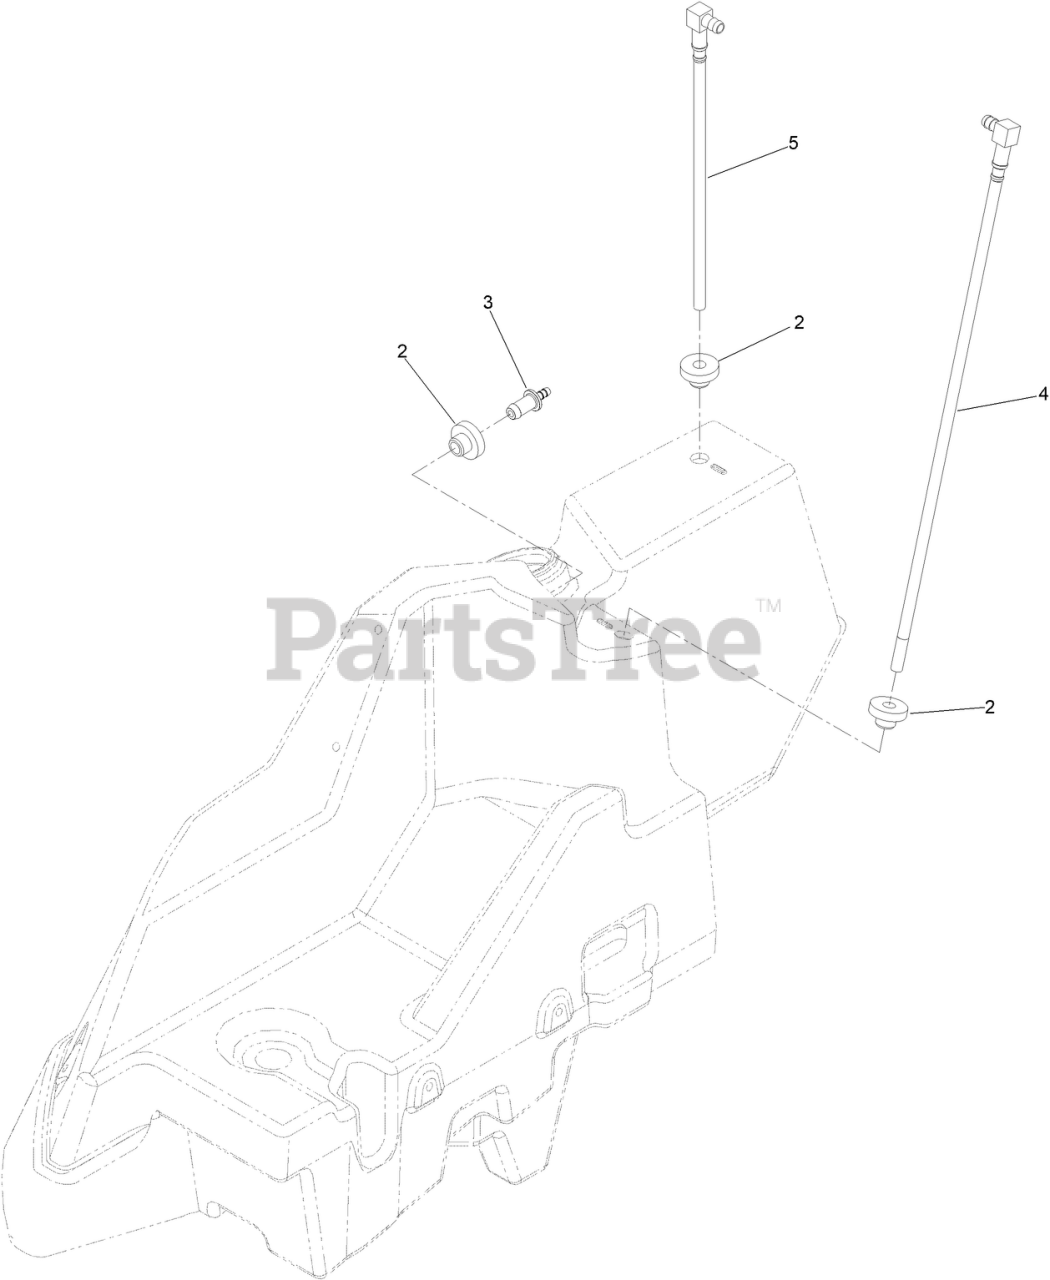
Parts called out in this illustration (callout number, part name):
2	BUSHING
3	FITTING-ORIFICE, STRAIGHT
4	PICK-UP-FUEL
5	RETURN-FUEL
